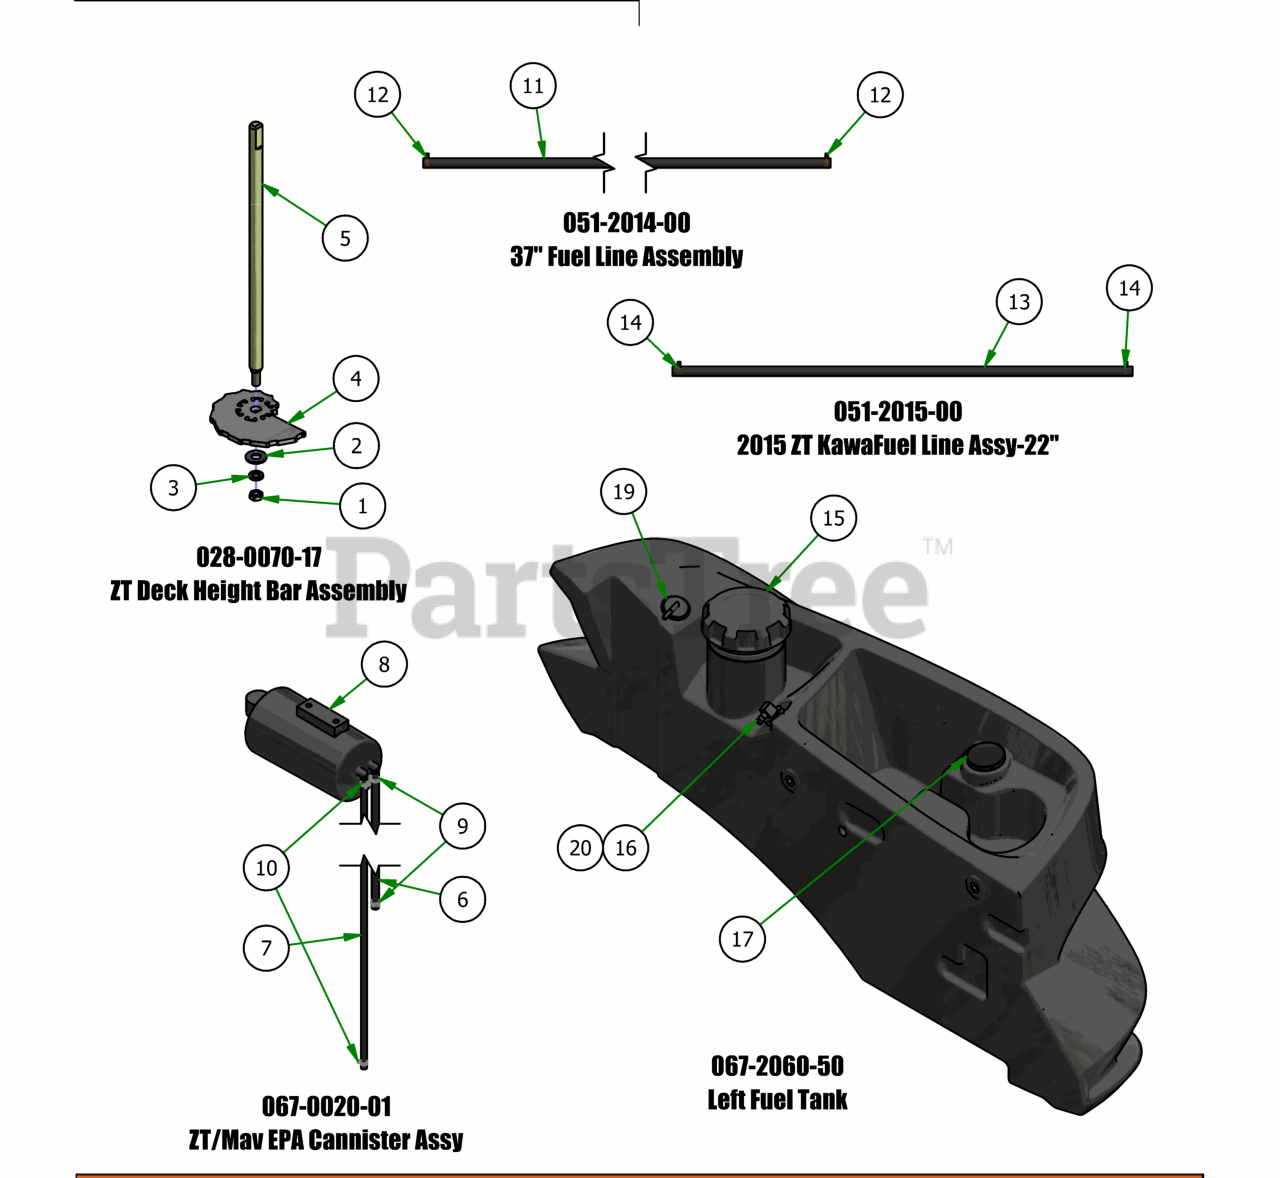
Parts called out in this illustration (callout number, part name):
1	3/8-24 HEX NUT ZINC YELLOW
2	3/8 FLAT WASHER USS (1" OD) ZINC
3	3/8 SPLIT LOCKWASHER ZINC
4	2017 MZ/ZT Cam Plate
5	2017 Deck Height Dial Rod ZT
6	1/4" Vinyl Tubing, 46" Long
7	3/16" Vinyl Tubing, 55" Long
8	Carbon Canister
9	3/16 Vinyl Clamp
10	3/16" Vinyl Hose Clamp
11	37" 1/4 Fuel Line
12	1/4 Fuel Hose Clamp
13	1/4 Fuel Line
14	1/4 Fuel Hose Clamp
17	Fuel Gauge w/Grommet
19	Rollover Valve W/Grommet
20	Pick-Up Grommet
